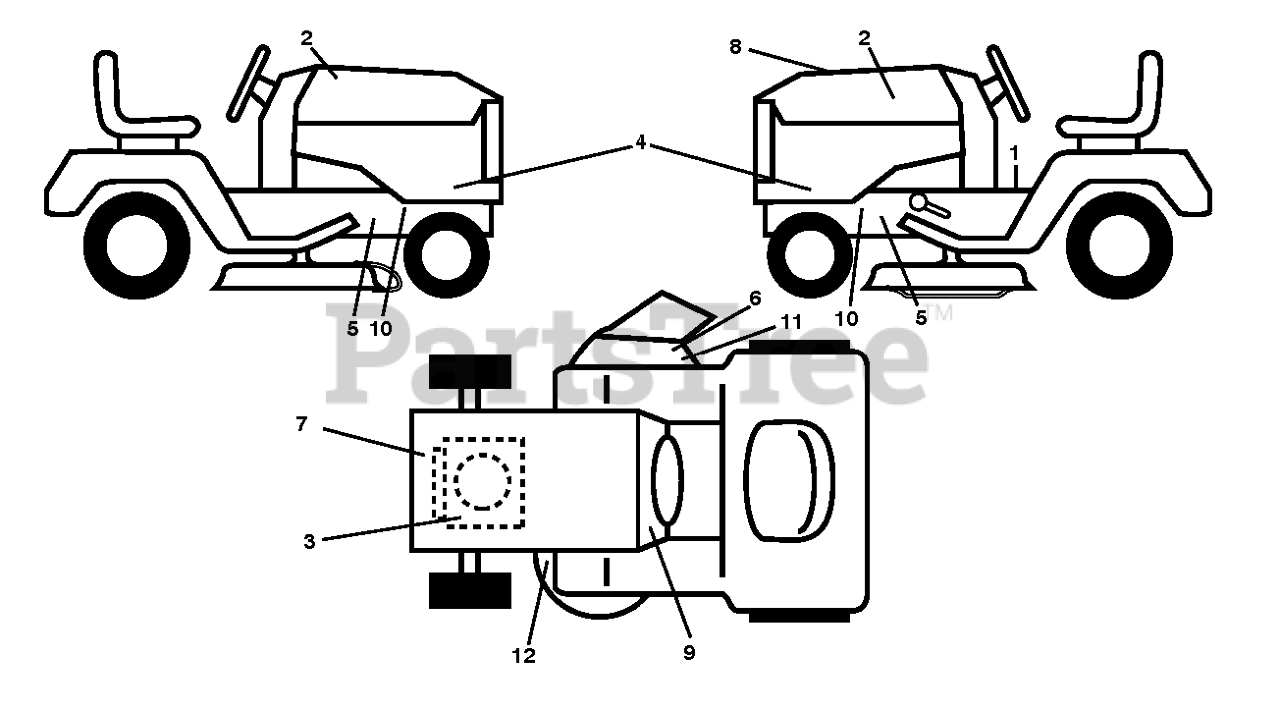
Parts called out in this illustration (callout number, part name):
1	DECAL TRACTOR SADDLE DECAL DEC
2	DECAL.WB.178MM.15.HUSQ.NEWBRAN
3	DECAL.ENGINE.WARNING
4	DECAL.SDPNL.HUSQLT.TS138
5	DECAL.CHASSIS.HOT.MUFFLER
6	DECAL, DECK DEFLECTOR, WARNING
7	DECAL.ENG.B&S.HS.500CC.382338
8	DECAL RPL.BSM31.HUSQ.TLW.38.K4
9	DECAL.SNOWFLAKE.MS498.HUSQ
10	DECAL.WARNING.SERVCE/FIRE
11	DECAL.DFLCTR.WARNNG.CTFNGR.SYM
12	DECAL.DECK.SCH.36,38,94.NONCR
